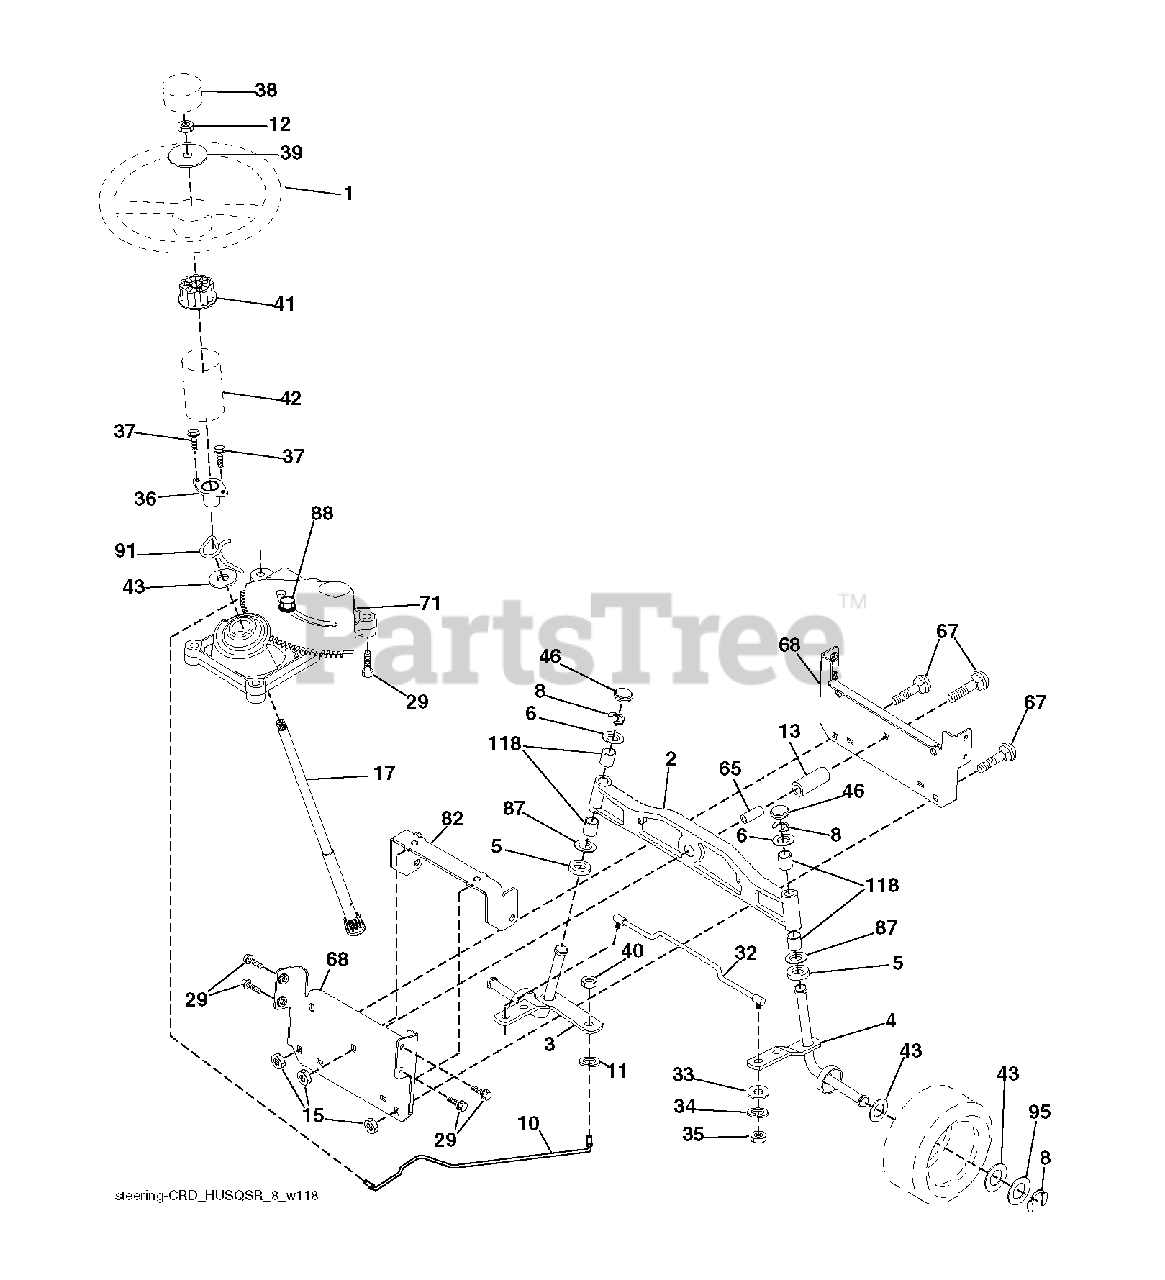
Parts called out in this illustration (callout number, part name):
1	WHEEL.STEERING.STDSRR.BLK/OV
2	AXLE.ASM.LT.CAST.LGHTWGHT
3	SPINDLE.ASM.LH.15"TIRES
4	SPINDLE.ASM.RH.15"TIRES
5	THRUST WASHER
10	DRAGLINK.15".TIRES.2001
11	WASHER, LOCK 3/8
12	NUT.HEX.1/2-20
13	TUBE, PIVOT AXLE (2 2)
15	NUT
17	SHAFT ASM STRG
29	SCREW, 3/8-16X3/4
33	WASHER M
34	LOCKWASHER
35	NUT, CROWNLOCK
36	BUSHING, STRG. BLK
37	SCREW.TT.#10-32X.5.3/8.FLANGE
38	CAP.WHL.STRNG.STDSRRD.SRS.BLK
39	WASHER 9/16"ID, 2 3/8"OD
40	NUT CROWNLOCK 3/8-24
41	ADAPTER, WHEEL STNG..
42	DASH.STEALTH
46	CAP.SPINDLE.BLACK
65	SPACER.BRACE.AXLE
67	BOLT CARRIAGE
68	BRACE.AXLE.15"TIRES
71	STEERING ASM
82	BRACKET.SUSP.CHASSIS.FRONT.15
87	WASHER, FLAT .781 X 1 1/2"
88	BOLT, SHOULDER 7/16-20
91	CLIP.STEERING
95	WASHER.HARDENED
118	BUSHING, AXLE CAST
